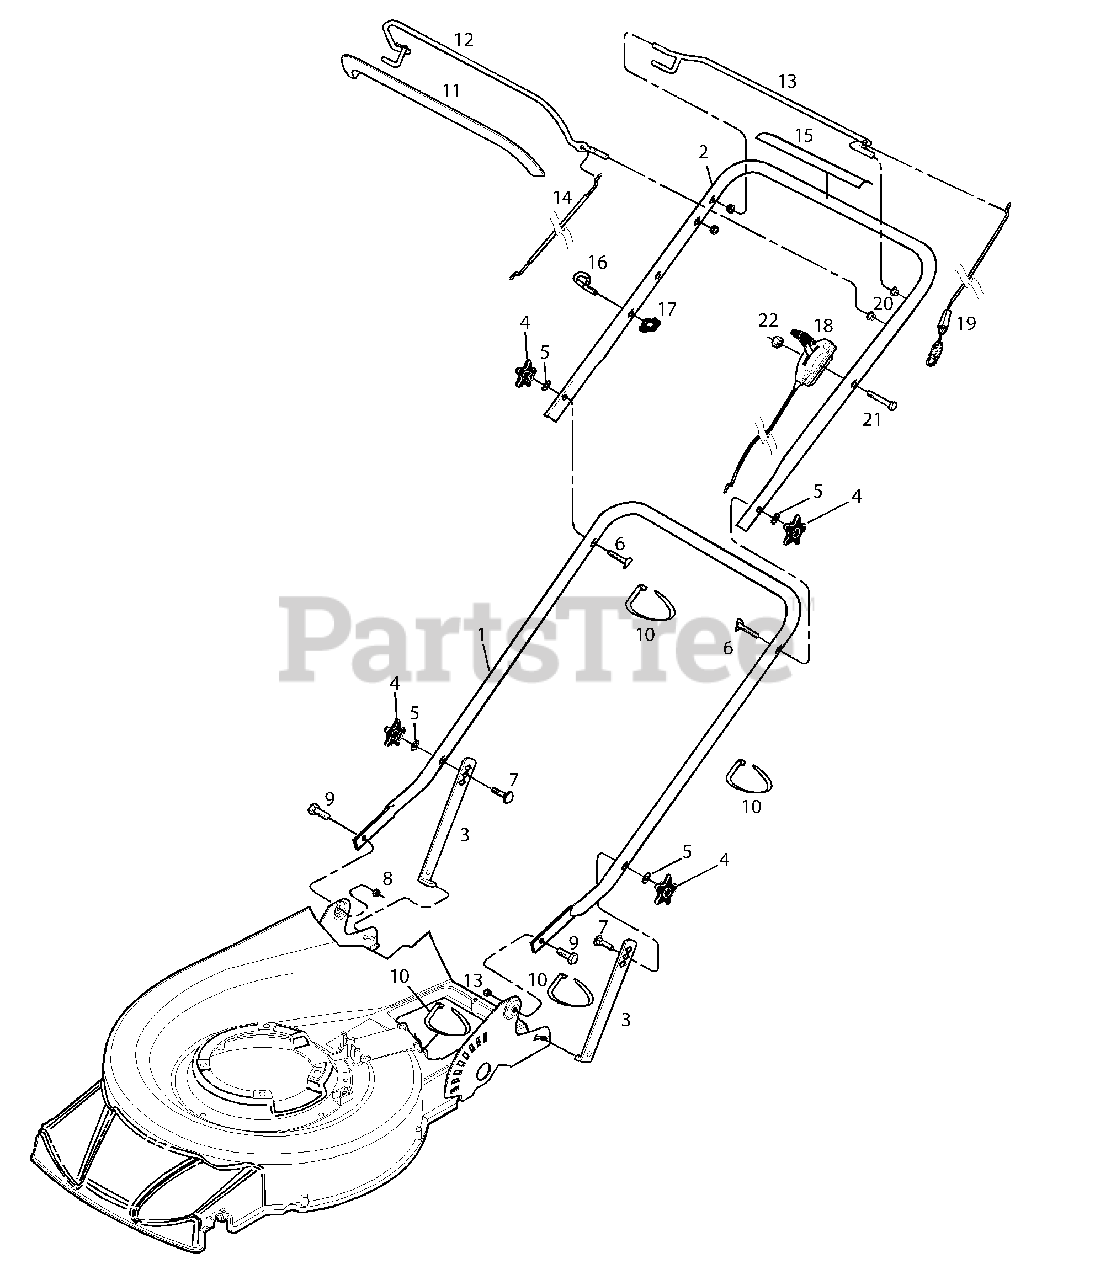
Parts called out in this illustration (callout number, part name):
1	Lower Handlebar
2	Upper Handlebar
3	Handlebar Support Strut
4	Handlebar Adjustment Knob
5	Ext. Tooth Lock Washer, 5/16
6	Curved Head Screw, 5/16-18 x 1-3/4
7	Carriage Bolt, 5/16-18 x 1-3/4, Special
8	Hex Lock Nut, 3/8-16
9	Hex Hd. Screw, 3/8-16 x 3/4, GR. 5
10	Cable Tie
11	Bail Grip
12	Operator Presence Control Bail
13	Wheel Drive Bail
14	Operator Presence Control Cable
15	Decal - Bail Operating Instructions
16	Rope Guide
17	Wing Knob, 1/4-20
18	Speed Control Lever/Cable
19	Drive Control Cable
20	Bushing, Nyliner
21	Hex Hd. Screw, M6
22	Hex Nut, M6
